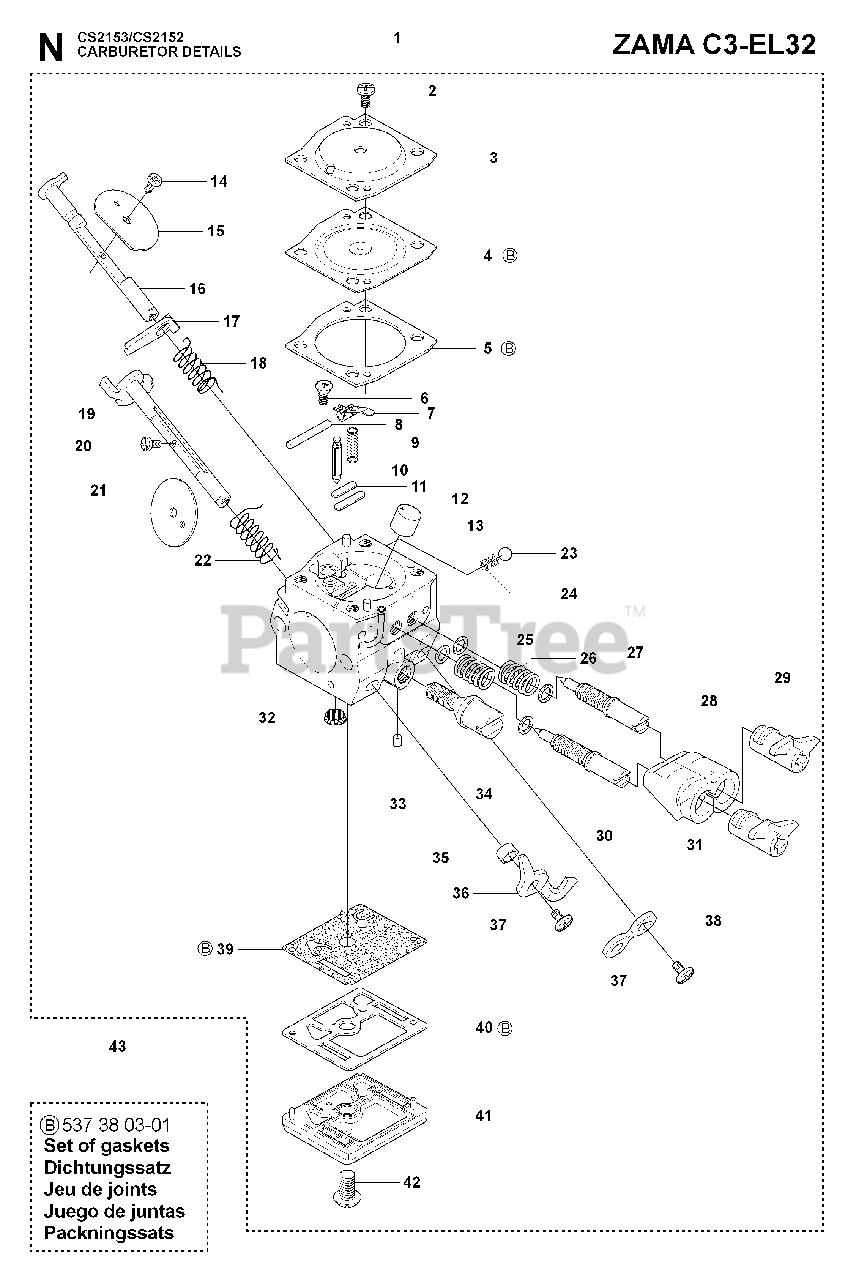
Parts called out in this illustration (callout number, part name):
1	CARBURETOR
4	DIAPHRAGM
8	PIN FULCRUM
15	CHOKE FLAP
16	CHOKE SHAFT
17	THROTTLE LOCK
19	THROTTLE SHAFT
21	THROTTLE FLAP
26	SPRING
29	LIMITER CAP
30	LOW SPEED NEEDLE
31	LIMITER CAP
34	IDLE SCREW
35	BUSHING *
39	PUMP DIAPHRAGM
43	GASKET SET
